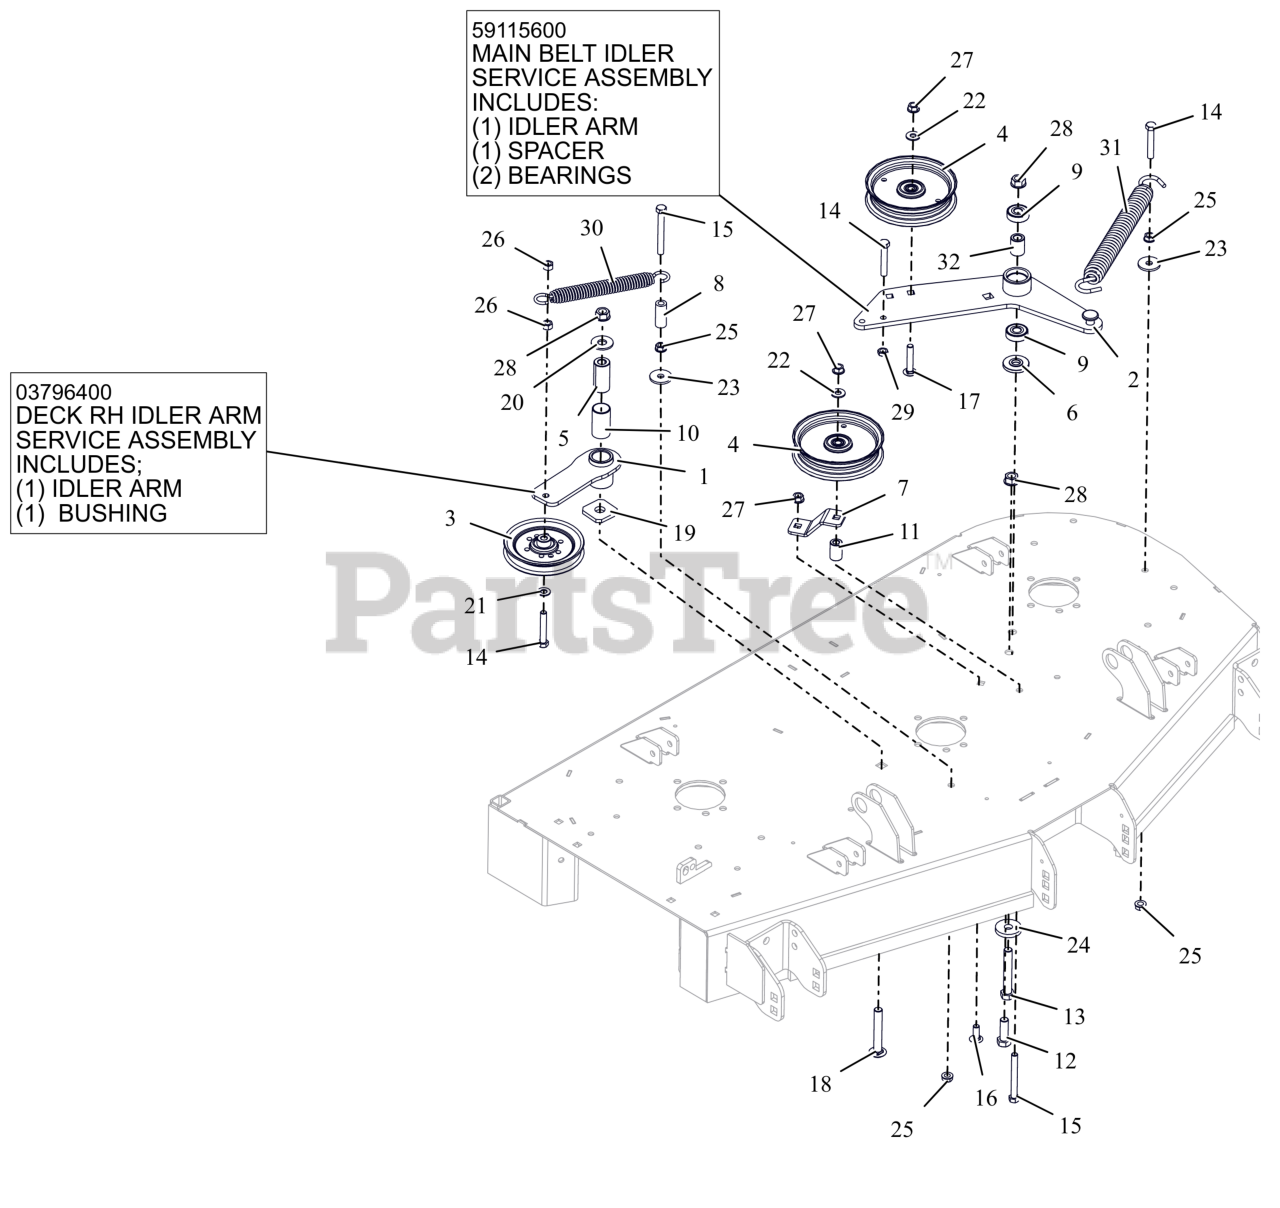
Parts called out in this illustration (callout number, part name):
1	WMT, IDLER ARM - BLACK
1	ASM, IDLER ARM (DECK)
2	WLDMT, DECK PTO IDLR ARM
2	ASSEMBLY, MAIN BELT IDLER
3	IDLER, V, 5.00X.38
4	IDLER- FLAT - 5.00" X .75"
5	BSHG, SPCR .502X.997X2.03 PM
6	SPACER, IDLER ARM
7	PTO FIXED IDLER MTG BRKT-ORG
8	HOSE, .38 X 1.65
9	BRG-BALL .500X1.38X.437
10	BSHG, 1.00X1.125X1.937
11	BUSHING, SLV .380X.750X1.190
12	BLT,HEX .50-13X1.50 G5 ZCC
13	BLT,HEX .50-13X3.25 G5 ZCC
14	BLT,HEX .38-16X2.25 G5 ZCC
15	BLT, HEX .38-16X3.25 G5 ZCC
16	BLT,RHSSN .38-16X1.00 G5 ZCC
17	BLT,RHSSN.375-16X2.00 G5 ZCC
18	BTL,RHSSN .500-13 X 3.25 G5 ZCC
19	WSHR-FLT .640X1.75X.250
20	WSHR,FLT .563X1.375X.109 ZCC
21	WSHR,FLT .406X.812X.065 ZCC
22	WSHR,FLT .375X.875X.083 ZCC
23	WSHR,FLT .406X1.375X.135 ZCC
24	WSHR-FL-STL .515X1.625X.250 YZ
25	NUT, SPNLK-FLG .38-16 G5 ZCC
26	NUT-LK-CTR .38-16 ZC120
27	NUT-LK-CTR-FLG .375-16 GF ZCC
28	NUT-LK-CTR-FLG .500-13 GG ZCC
29	NUT-JAM .375-16 G2 ZCC
30	SPRING- EXTENSION
31	SPRING, EXTENSION
32	SPACER .510 X .867 X 1.1485
